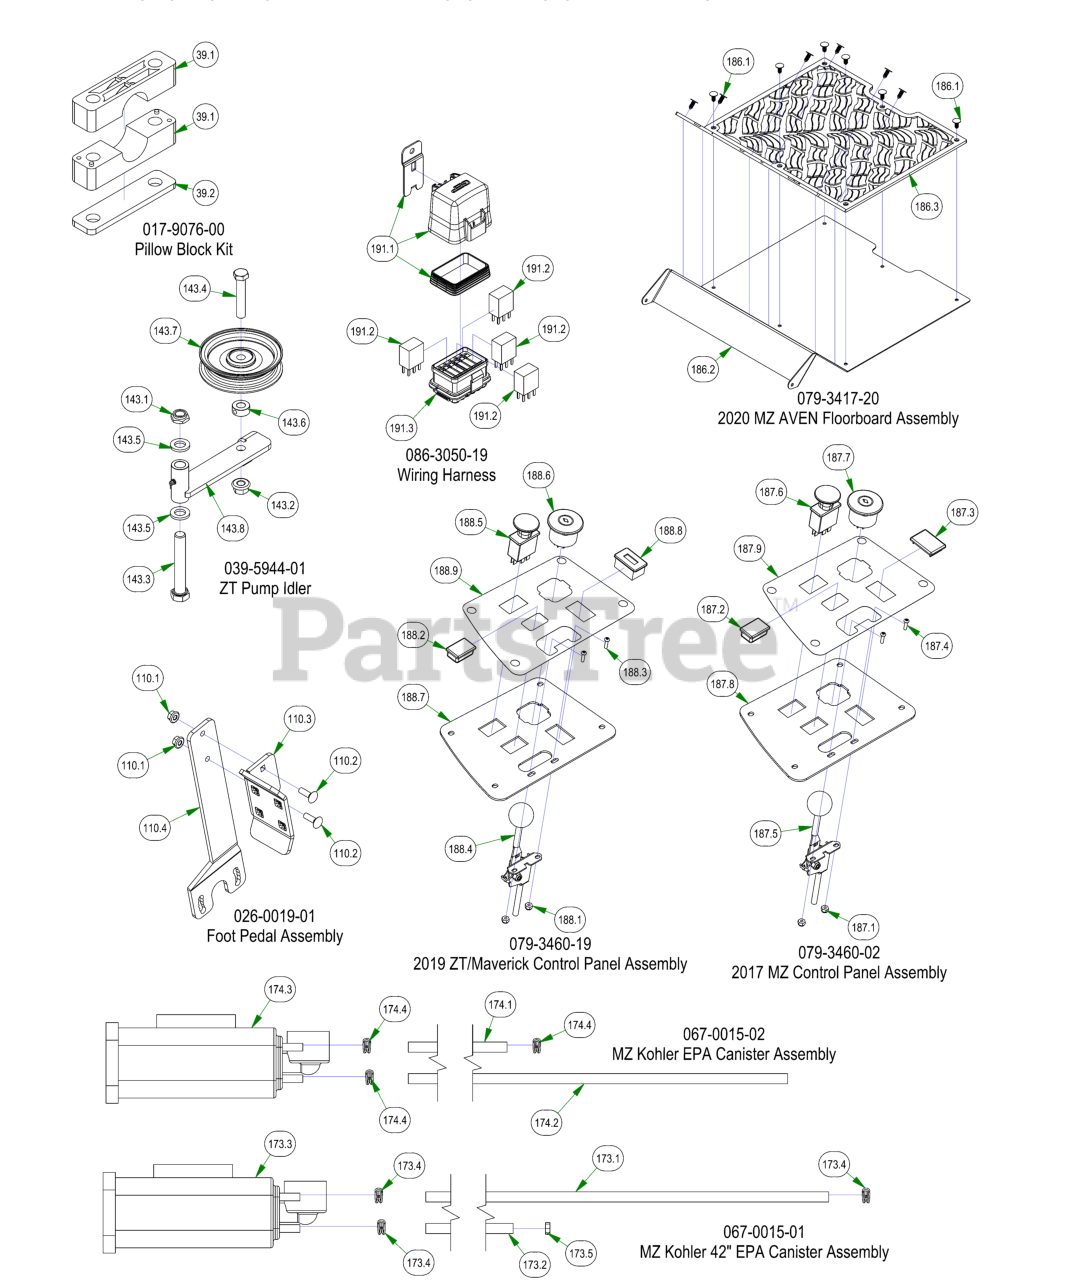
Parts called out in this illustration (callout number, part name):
39	Pillow Block Kit
39.1	Pillow Block MZ
39.2	Pillow Block Strap
110	Foot Pedal Assembly
110.1	5/16-18 NYLON INSERT FLANGE LOCKNUT ZINC
110.2	5/16-18 X 1 CARRIAGE BOLT (GR.8) ZINC
110.3	2017 MZ/ZT Shallow Foot Pedal
110.4	2017 MZ/ZT Deck Pedal Lever
143	ZT Pump Idler
143.1	5/8-11 NYLON INSERT JAM LOCKNUT ZINC
143.2	1/2-13 NYLON INSERT FLANGE LOCKNUT ZINC
143.3	5/8-11 X 4 HEX CAP SCREW (GR.8) ZINC YELLOW
143.4	1/2-13 X 2-3/4 HEX CAP SCREW (GR.5) ZINC
143.5	.635 ID X 1.120 OD X .140 THICK FLAT WASHER NYLON
143.6	1/2 SOLID SHAFT COLLAR (W/1 SET SCREW) ZINC
143.7	4 3/4" Idler Pulley
173	MZ Kohler 42" EPA Canister Assembly
173.1	3/16 Vinyl Tubing, 53"
173.2	3/16" Clear Vinyl Tubing, 44"
173.3	Carbon Canister for Magnum/MZ
173.4	8.6mm Hose Clamp
173.5	3/16" Vinyl Hose Clamp
174	MZ Kohler EPA Canister Assembly
174.1	3/16 Vinyl Tubing, 44"
174.2	3/16" Clear Vinyl Tubing, 52"
174.3	Carbon Canister for Magnum/MZ
174.4	8.6mm Hose Clamp
186	2020 MZ AVEN Floorboard Assembly
186.1	Ratchet Fastener
186.2	MZ/ZT 2017 Floorboard
186.3	2021 Maverick Floor Mat W/ Reaper Tread
187	2017 MZ Control Panel Assembly
187.1	10-24 Nylon Insert Locknut Zinc Orange Nylon
187.2	Light Plug
187.3	42 MZ Light Plug
187.4	10-24 X 5/8 BS Button Head Bolt
187.5	Throttle Lever Assembly
187.6	PTO Engager
187.7	Ignition Switch
187.8	2014 ZT Control Panel
187.9	Rambler Instrument Panel Decal
188	2019 ZT/Maverick Control Panel Assembly
188.1	10-24 Nylon Insert Locknut Zinc Orange Nylon
188.2	Light Plug
188.3	10-24 X 5/8 BS Button Head Bolt
188.4	Throttle Lever Assembly
188.5	PTO Engager
188.6	Ignition Switch
188.7	2014 ZT Control Panel
188.8	Tachometer
188.9	Rambler Instrument Panel Decal
191	Wiring Harness
191.1	Relay Block Cover Replacement Kit
191.3	Wiring Harness
